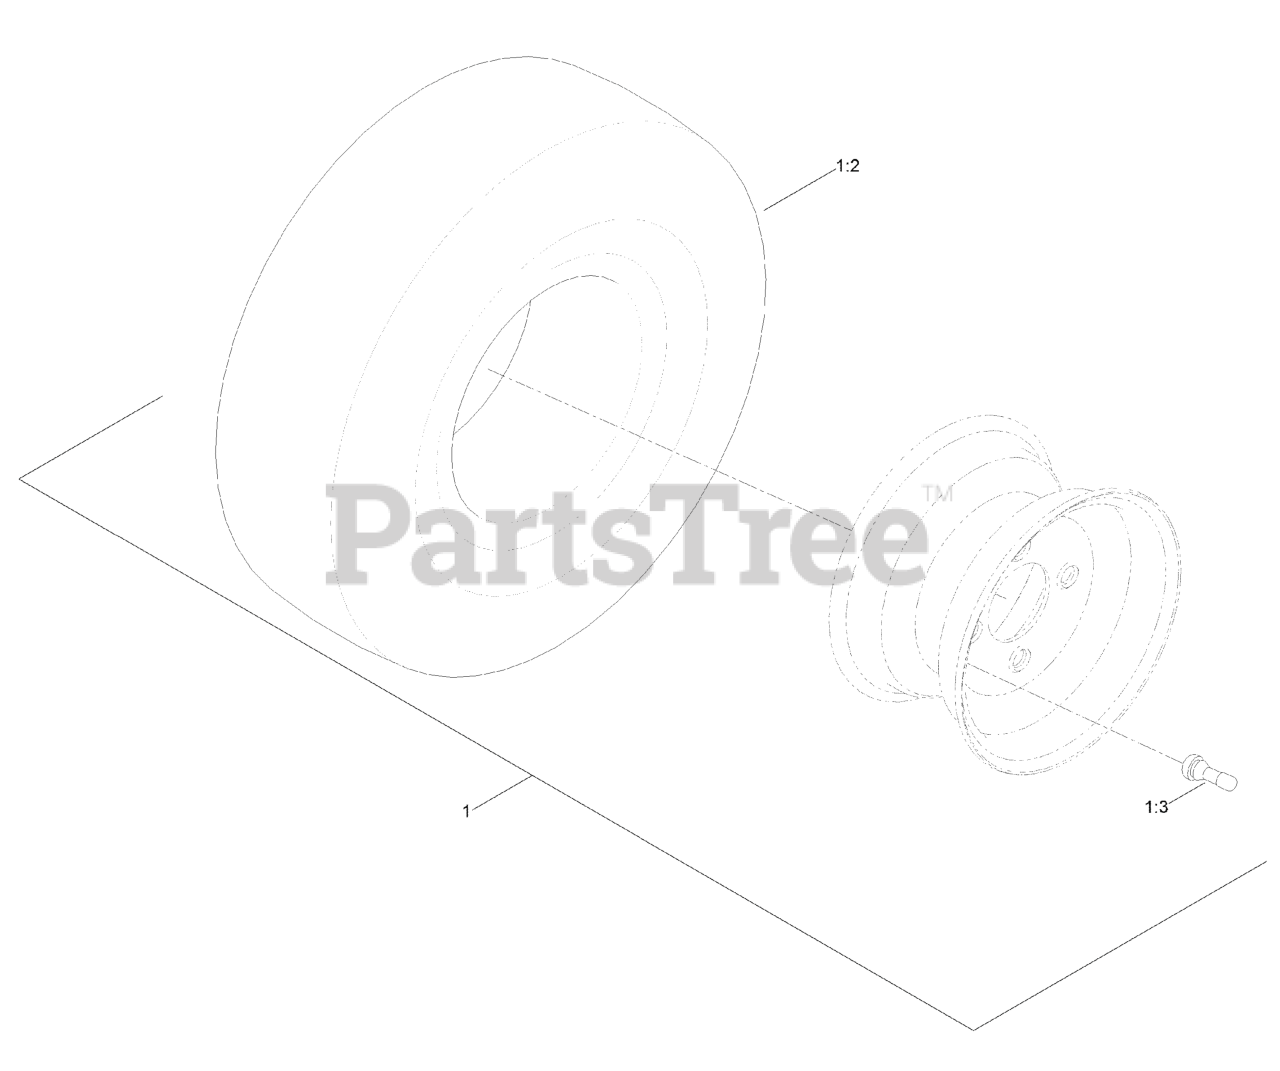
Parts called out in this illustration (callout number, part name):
1	2 PLY TIRE AND WHEEL ASM
1:2	TIRE-2 PLY
1:3	Stem-Valve
